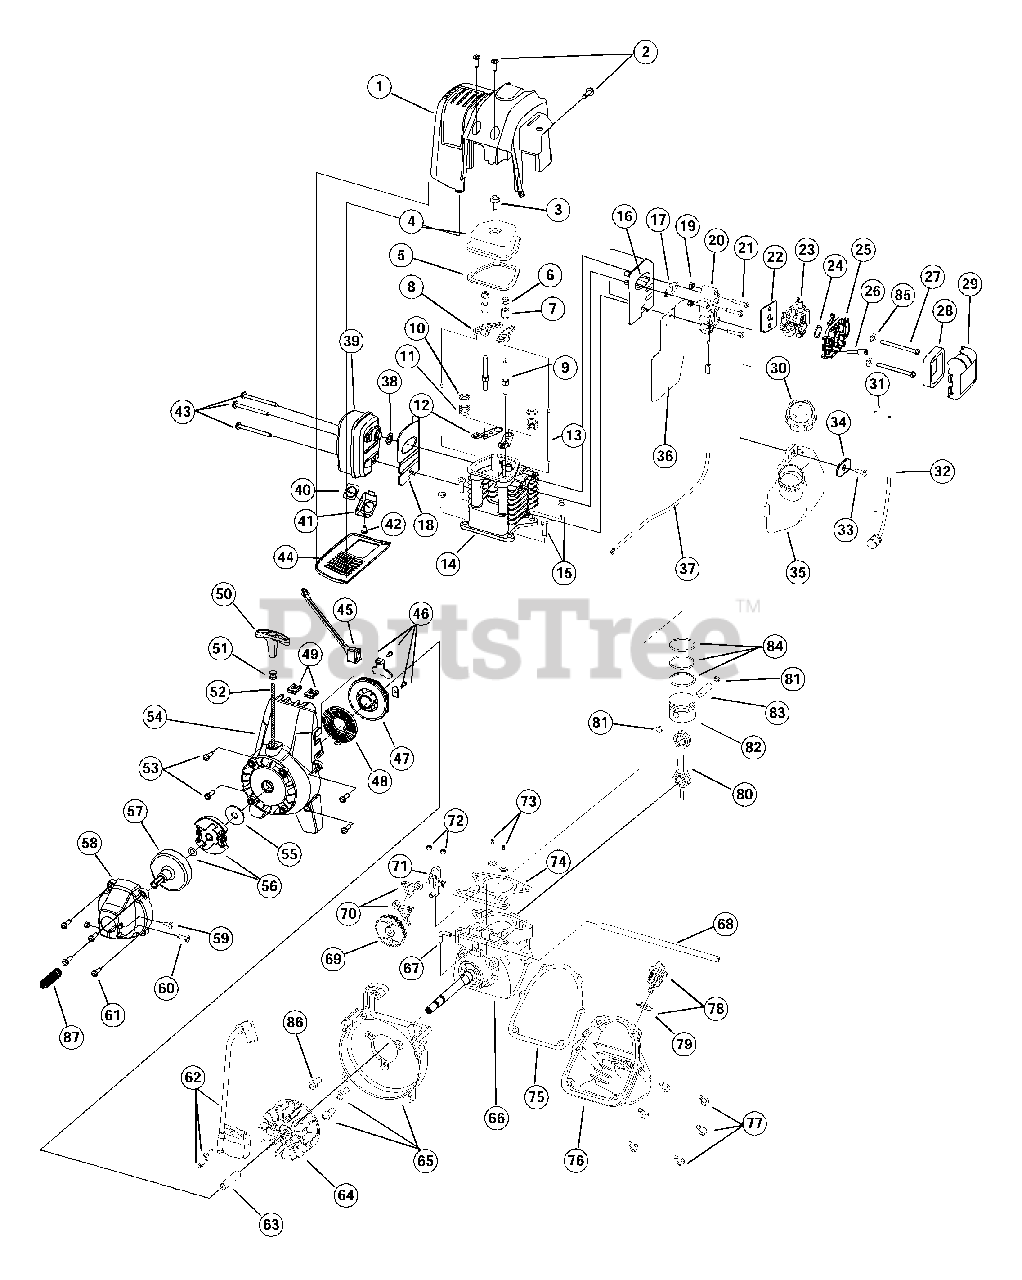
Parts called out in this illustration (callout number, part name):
1	Engine Cover
2	Engine Cover Screws
3	Valve Cover Screw
4	Valve Cover
5	Valve Cover Gasket
6	Rocker Adjustment Nut
7	Rocker Arm Pivot
8	Rocker Arm
9	Rocker Arm Stud
10	Valve Spring Retainer
11	Valve Spring
12	Push Rod Guide
13	Push Rod
14	Cylinder Head Assembly
15	Cylinder Screw
16	Intake Baffle
17	Carburetor Mount Gasket
18	Muffler Baffle
19	Nut
20	Carburetor Mount
21	Carburetor Mount Screw
22	Carburetor Gasket
23	Carburetor with Primer
24	O-Ring, Carburetor
25	Air Filter/Choke Cover Assembly
26	Breather Tube
27	Air Filter Mounting Screw
28	Air Filter
29	Air Filter Cover
30	Fuel Cap
31	Fuel Return Line
32	Fuel Pick-Up Line with Filter
35	Fuel Tank Assembly
36	Fuel Tank Shield
37	Throttle Cable
38	Muffler Gasket
39	Muffler
40	Spark Arrestor Screen
41	Screen Cover
43	Muffler Mounting Screw
44	Muffler Cover
46	Pal Nut Retaining Ring
47	Recoil Pulley
48	Recoil Spring
49	Nut Clip
50	Pull Handle
51	Rope Guide
53	Starter Housing Screw
54	Starter Housing Assembly
55	Clutch Washer
56	Clutch with Spacer
57	Clutch Drum
58	Clutch Cover
59	Anti-Rotation Screw
60	Screw
61	Clutch Cover Screw
62	Ignition Module with Screws
64	Flywheel
65	Shroud Assembly with Screws
66	Crankcase Assembly
67	90° Elbow
68	Breather Hose
69	Cam Gear
70	Cam Follower
71	Cam Bracket
72	Cam Bracket Screw
73	Valves, Intake and Exhaust
74	Cylinder Gasket
75	Oil Pan Gasket
76	Oil Pan
77	Oil Pan Screw
78	Dipstick Assembly
80	Connecting Rod
81	Wrist Pin Button
82	Piston
83	Wrist Pin
84	Piston Ring Set
87	Compression Spring
88	Grommet
